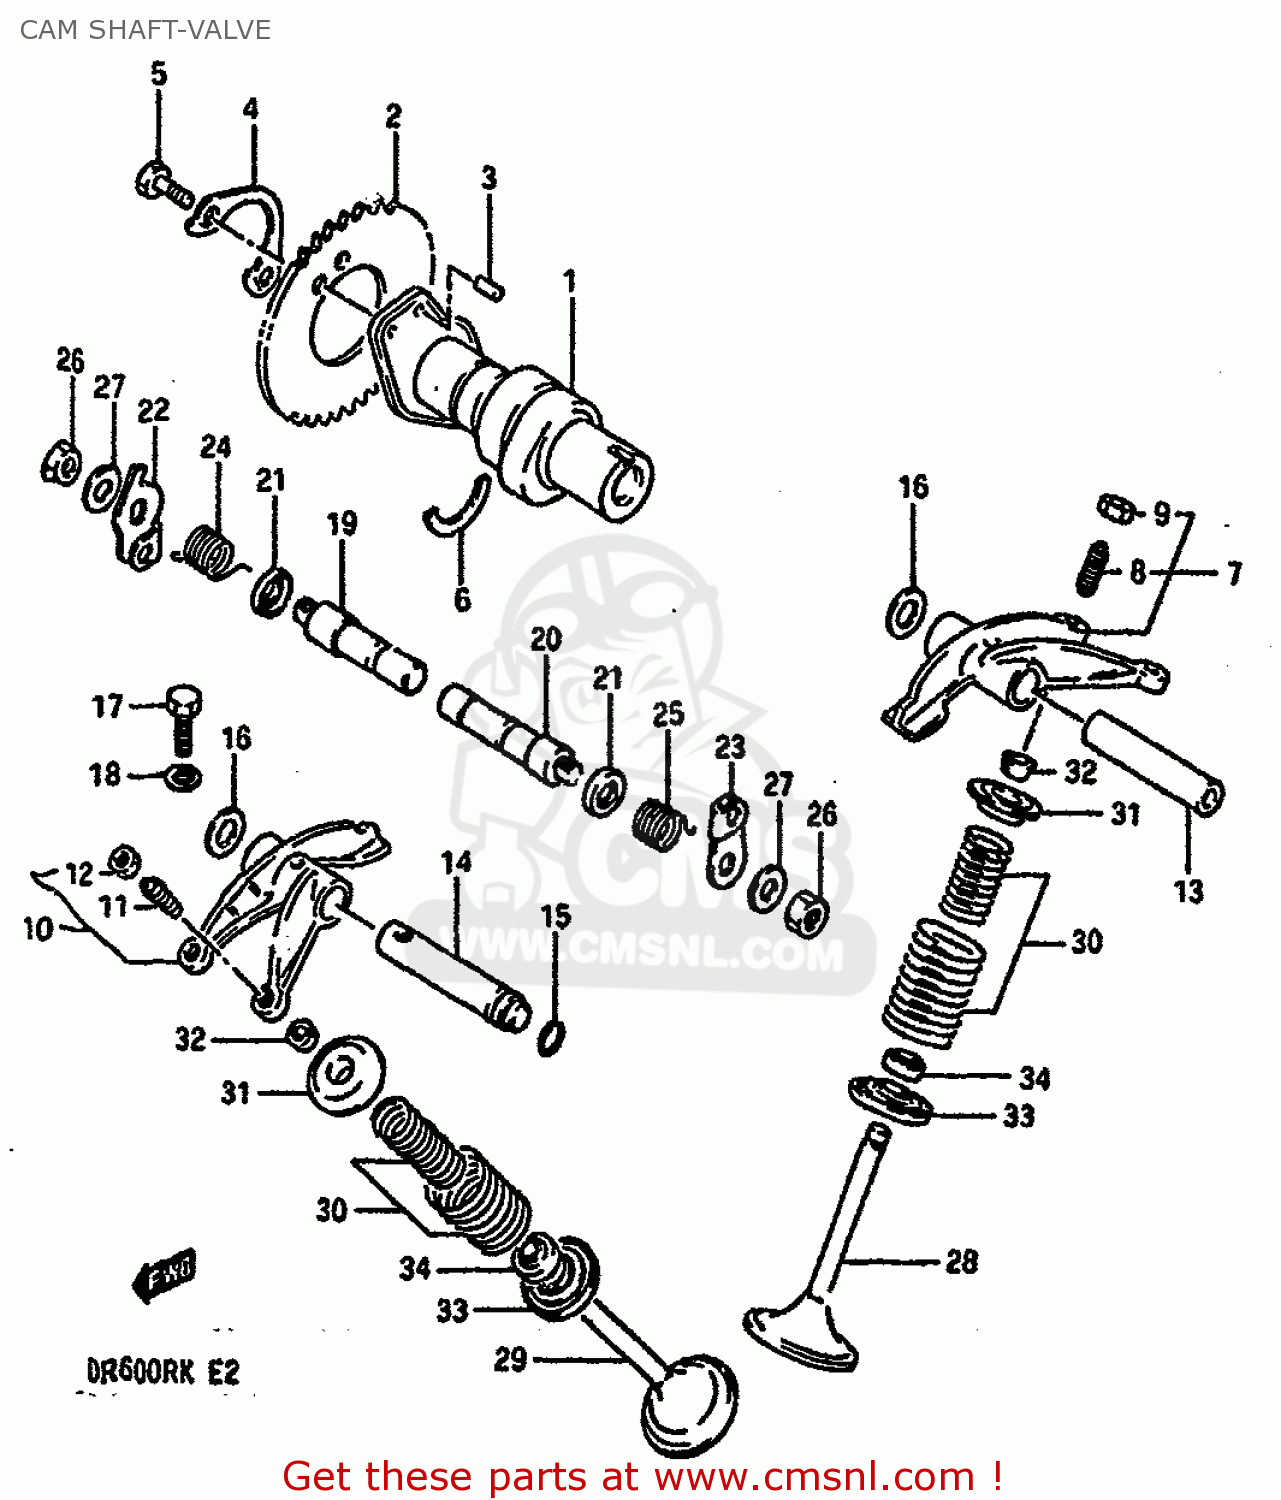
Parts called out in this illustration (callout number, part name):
1	CAMSHAFT
2	SPROCKET,CAMSHAFT(NT:42)
3	PIN
4	WASHER,CAM CHAIN SPROCKET
5	BOLT(6X12.5)
6	C RING
7	ARM,VALVE ROCKER,INTAKE
8	SCREW,TAPPET ADJUSTING
9	NUT,ADJUSTING SCREW
10	ARM,VALVE ROCKER EXHAUST
11	SCREW,TAPPET ADJUSTING
12	NUT,ADJUSTING SCREW
13	SHAFT,VALVE ROCKER ARM
14	SHAFT,EXHAUST VALVE ROCKER ARM
15	O RING(D:1.9,ID:8.6)
16	WASHER
17	BOLT 6X30
18	GASKET(5.8X13X1.2) (NAS)
19	SHAFT,DECOMP LH
20	SHAFT,DECOMP,L
21	OIL SEAL
22	LEVER,DECOMP SHAFT
23	LEVER,DECOMPRESSION SHAFT,LEFT
24	SPRING
25	SPRING
26	NUT 8MM
27	WASHER
28	VALVE,INTAKE
29	VALVE,EXHAUST
30	SPRING SET,VALVE
31	RETAINER,VALVE SPRING
32	COTTER VALVE
33	SEAT,VALVE SPRING
34	SEAL,OIL(7X14.4X9)
